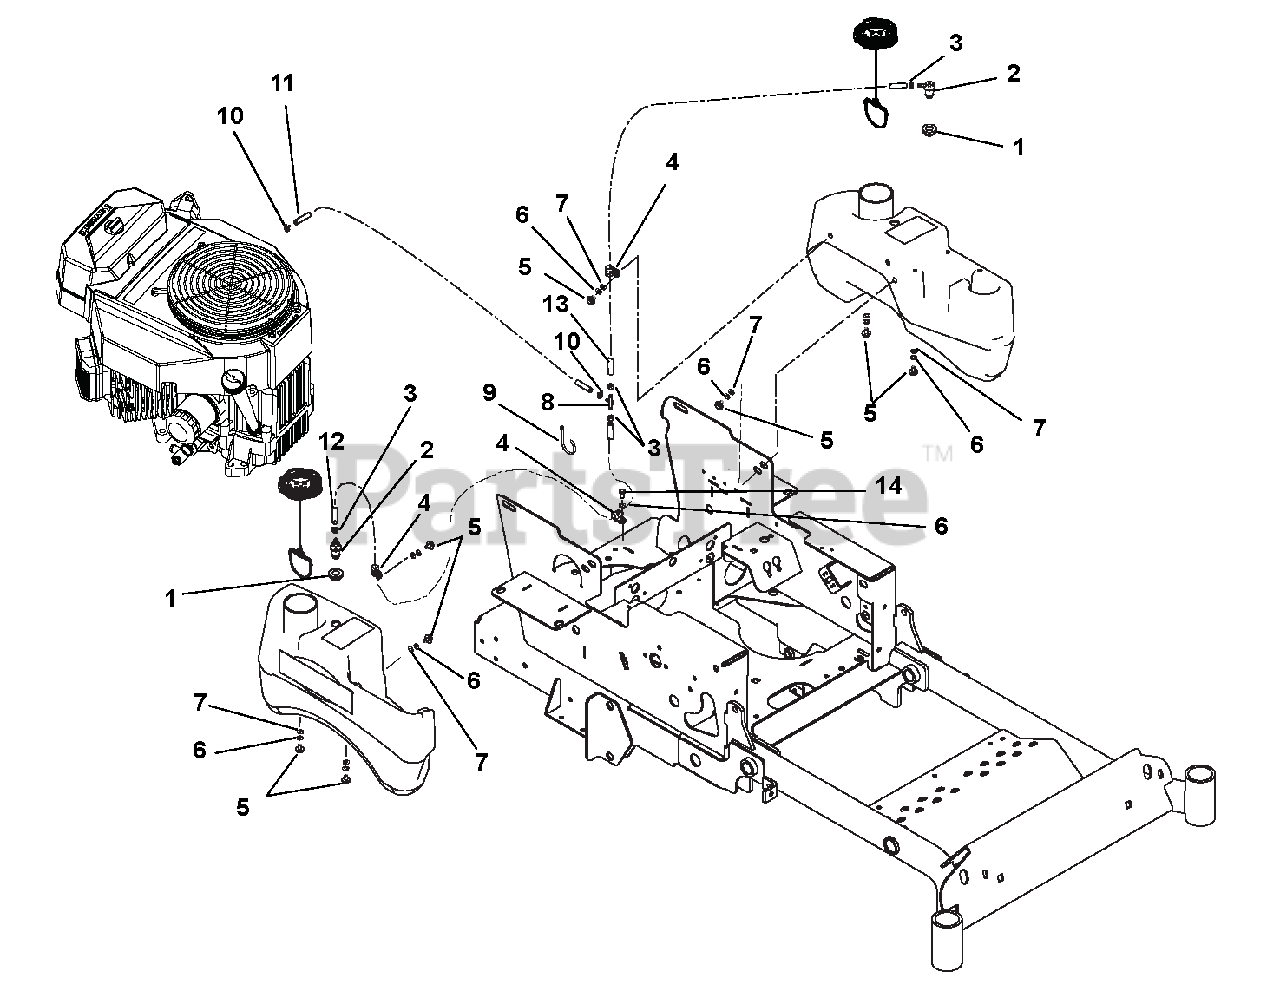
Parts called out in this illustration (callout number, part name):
1	GROMMET, REMOTE VENT NITRILE
2	VALVE, COMBINATION
3	CLAMP, FUEL LINE
4	CLAMP, CUSHIONED STEEL
5	BOLT-HEX.31-18X.875 YWZC GR5
6	@WSHR-LK .31X.078 REG YWZC
7	@WSHR-FL-STL.38X.875X.083 YWZC
8	TEE,1/4HS RUN X 3/16HS BRANCH
9	CABLE TIE LG 5-1/2
10	CLAMP-HOSE, SPRING .188
11	HOSE, .188 LOW-PERM BULK GAS
12	HOSE, .25 LOW-PERM BULK GAS
13	HOSE, .25 LOW-PERM BULK GAS
14	@BLT-HEX M8-1.25X20 YWZC
